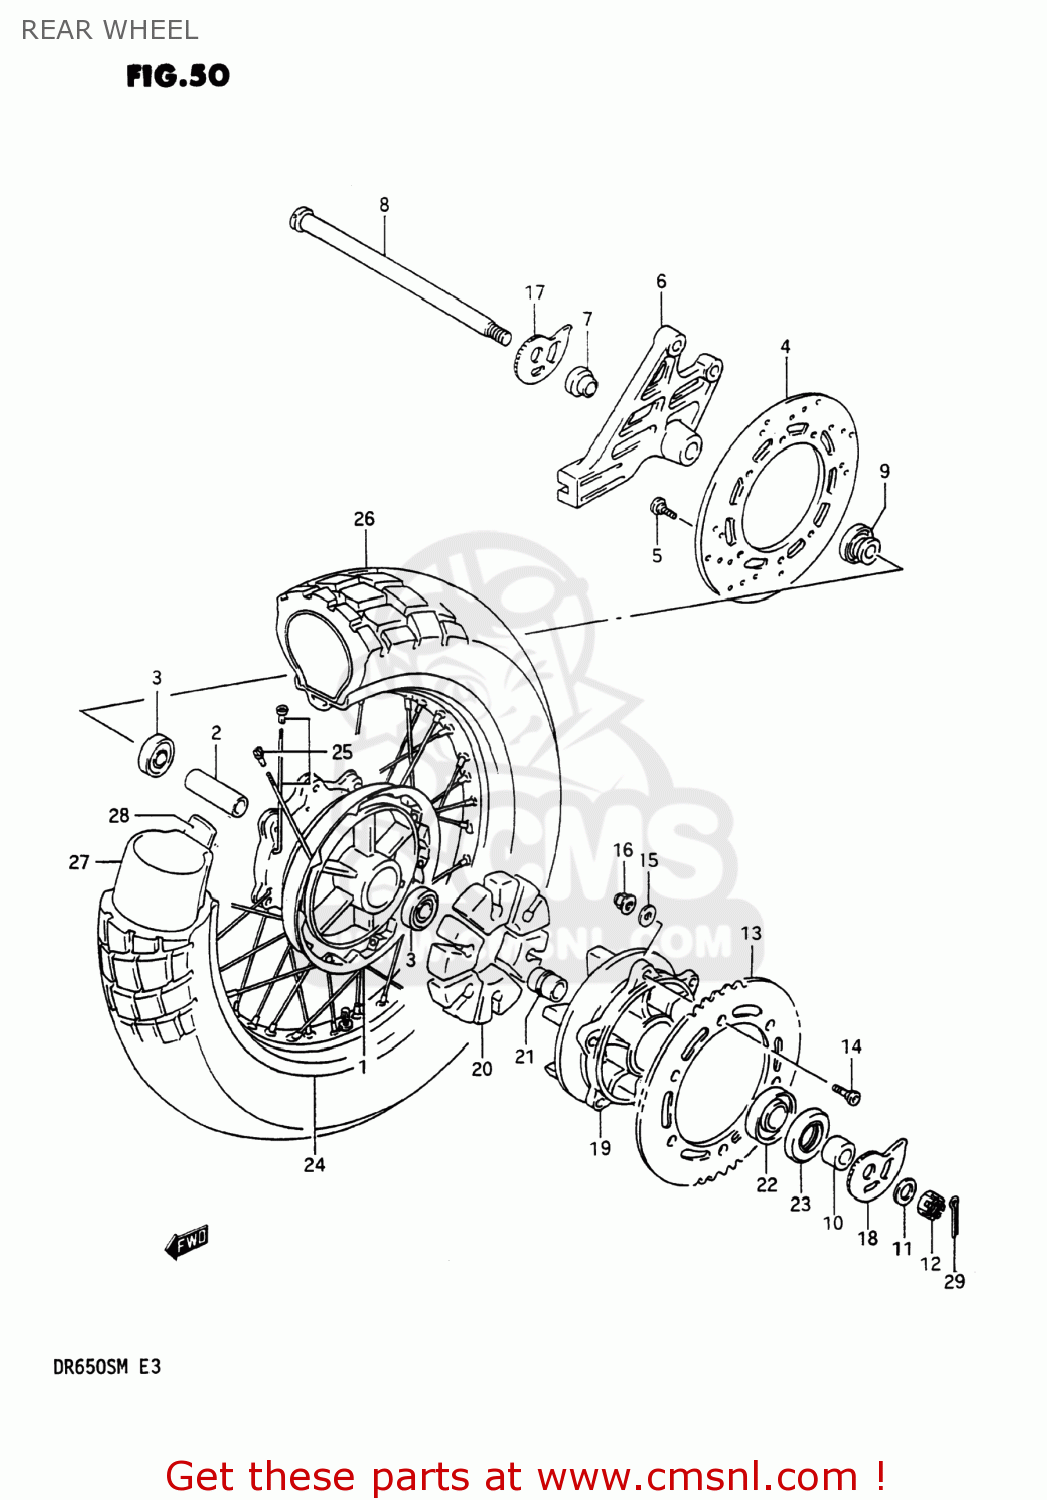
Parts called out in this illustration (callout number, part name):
1	HUB COMP,REAR WHEEL
2	SPACER(17.5X25X78)
3	BEARING
4	DISC,RR BRAKE
5	BOLT,BRAKE DISC
6	BRACKET,RR CALIPER
7	SPACER (17X21X10)
8	AXLE,REAR
9	SPACER,RR AXLE,L
10	SPACER(17X33X22.4)
11	WASHER (17X30X3.2)
12	NUT
13	SPROCKET,REAR
14	BOLT(8X30.5)
15	WASHER
16	NUT
17	ADJUSTER,CHAIN
18	PLATE,CHAIN ADJUSTER
19	DRUM,REAR SPROCKET
20	ABSORBER,RR HUB SHOCK
21	RETAINER,RR SPROCKET DRUM
22	BEARING(25X62X17)
23	SEAL,OIL(33X62X7)
24	RIM,REAR WHEEL (17XMT2)
25	SPOKE SET,RR
26	TIRE
27	TUBE ASSEMBLY,WHEEL,INNER
28	PROTECTOR,WHL INR TUBE
29	PIN,COTTER
